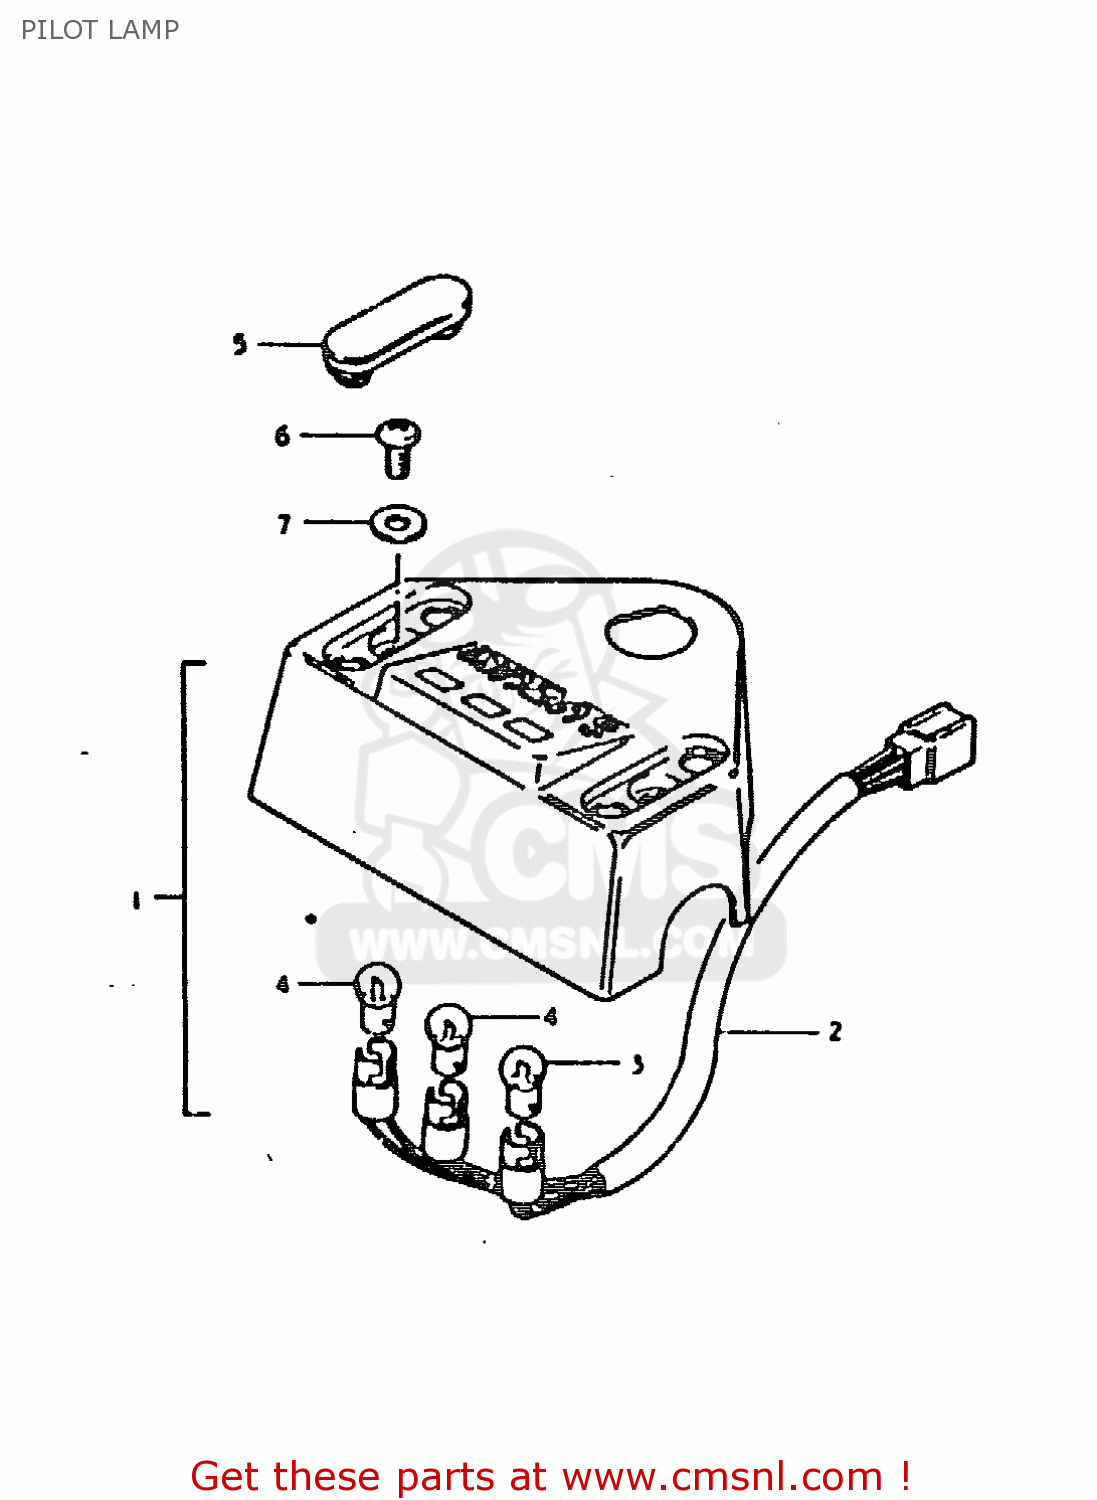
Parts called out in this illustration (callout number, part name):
1	CASE,PILOT BULB
2	SOCKET
3	BULB(6V1.7W,STANLEY,A61A)
4	BULB(6V/3W)
5	CAP,PILOT BOX BOLT
6	SCREW 6X12
7	WASHER
